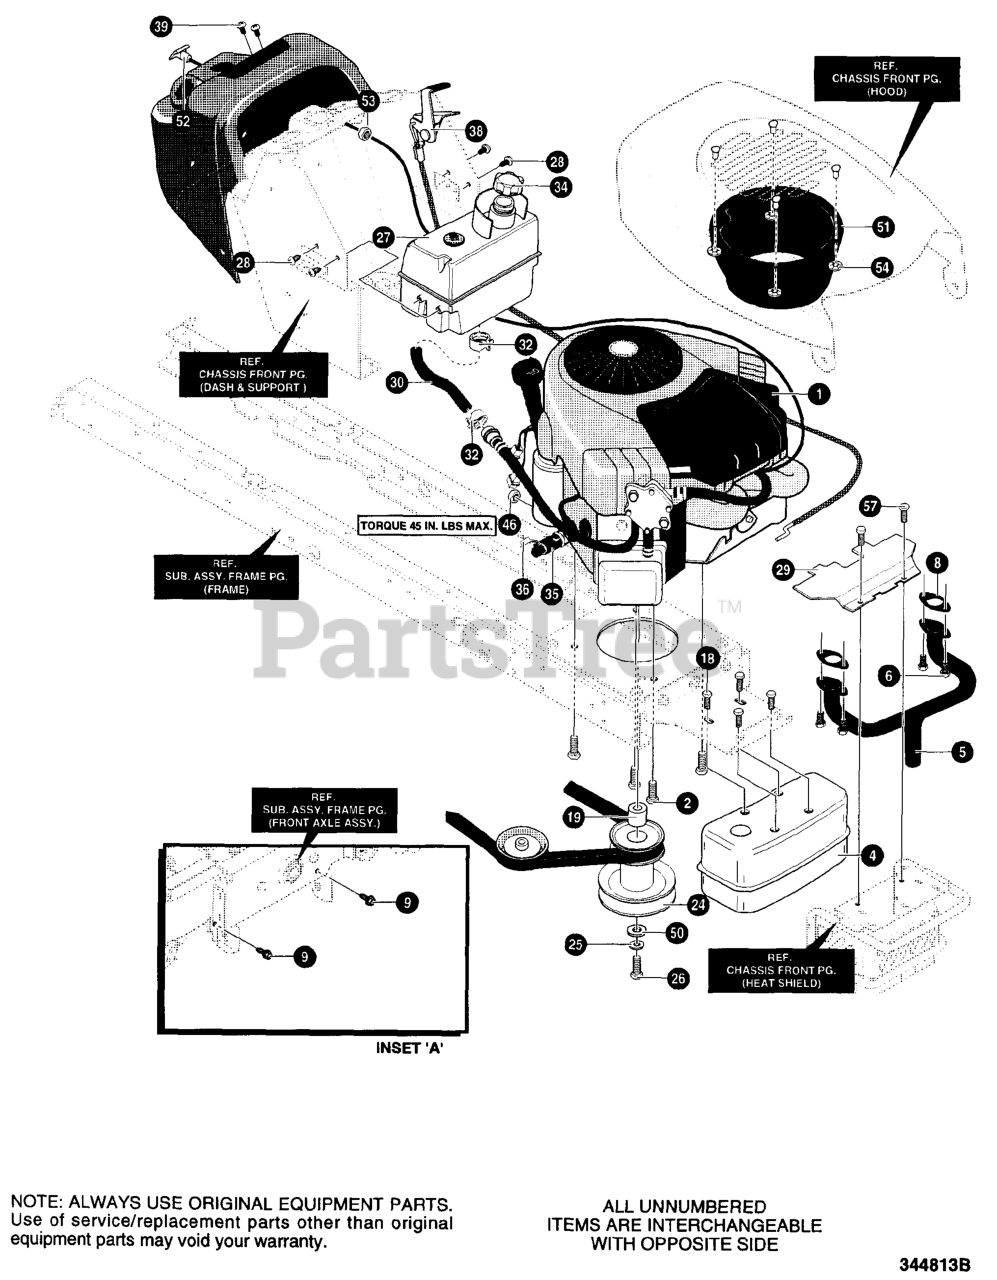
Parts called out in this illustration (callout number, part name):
1	ENGINE
4	MUFFLER, TWIN-CYLINDER
5	EXHAUST MANIFOLD
8	GASKET
18	SCRW
19	SPACER, SLEEVE
24	PULLEY, STACK
25	WASHER
27	FUEL TANK
29	SHIELD, HEAT
30	TUBING
32	CLAMP, FUEL LINE
34	FUEL CAP
35	OIL DRAIN VALVE ASSEMBLY
36	CAP, OIL DRAIN VALVE
38	THROTTLE CONTROL
46	NUT, 1/4-20
50	WASHER
51	PLENIUM
52	CHOKE CONTROL
54	PUSHNUT
57	SCREW
